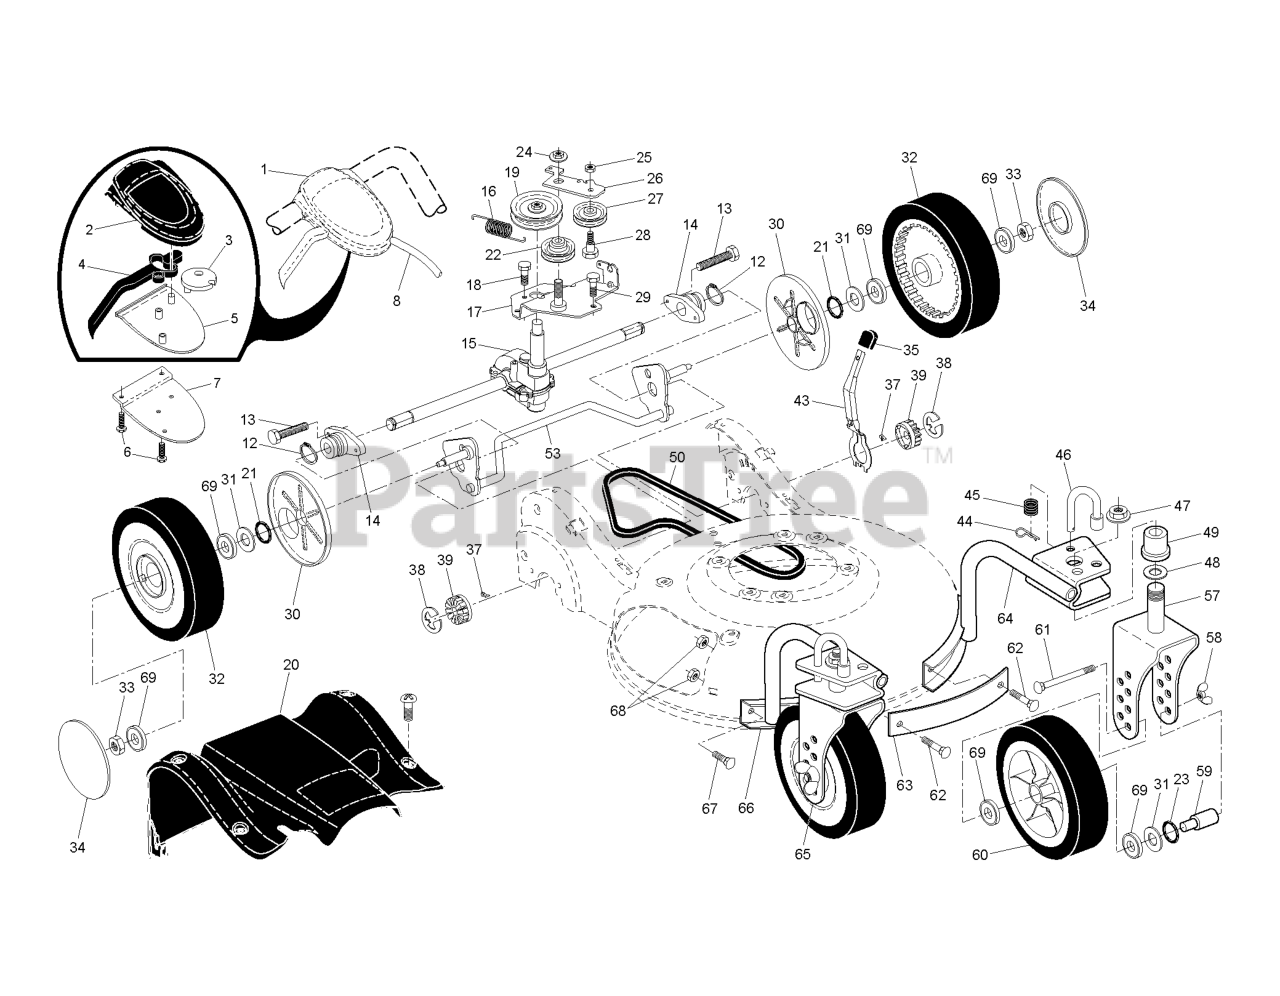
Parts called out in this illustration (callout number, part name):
1	Drive Control Assembly, Complete
2	COVER TOP AUTO WALK CONTROL
3	PULLEY.CAM.DRIVE.CONTROL.HV
4	LEVER.BLACK
5	COVER BOTTOM AUTO WLK CONTROL
6	SCREW, PHILLIPS HEAD 10 X 5/8
7	BRACKET.DRIVE.CONTROL.MOUNT.BL
8	ASM.CABLE.
12	RETAINING RING (2 2)(3 2)
13	HINGE SCREW
14	BEARING / AXLE SUPPORT
15	TRANSMISSION.21.HV.RWGD.AW/EZ
17	BRACKET, GEAR CASE / DRIVE
19	RP PULLEY.DRIVE.EZ
20	COVER.DR.ASM.408006X418.CE
21	O-RING..070X.487.NEOPRENE
22	PULLEY.IDLER.V-BELT
23	O-RING
24	NUT.HEX.FLANGE.3/8-16.LOCKNUT
25	NUT.CENTERLOCK.5/16-
26	ARM.IDLER.BZP
27	IDLER PULLEY
28	SHOULDER BOLT
29	SCREW 14-20 X 5/8
30	DUST COVER, WHEEL
31	WASHER.FLAT.1/2
32	WHEEL.9X2.25.LP.TIGER.BLACK
33	NUT.HEX.FLANGE.3/8-16.LO(3 2)
34	HUBCAP.WHEEL.5.SPOKE.SILVER
35	KNOB.SELECTOR.SPRING.BLACK(3 2
37	PAWL, DRIVE
38	E-RING 7/16 RE
39	PINION.14.TEETH.FGD
43	LEVER, SELECTOR, HEIGHT, REAR
44	SPRING RETAINER
47	NUT.HEX.FLANGE.3/8-16.LOCKNUT
48	WASHER.FLAT.1/2
50	BELT, DRIVE
53	SHAFT.ASM.REAR.TORQUE.HV.BZP
57	BRACKET.WHEEL.ASM.LT.CASTER.OR
58	NUT.WING.5/16-18.YELLOW
60	WHEEL.9X2.25.LP.TIGER.SILVER
61	CARRIAGE BOLT
63	STRAP.FRONT.CASTER.ORANGE
64	SUPPORT.TUBE.ASM.LT
65	BRACKET.WHEEL.ASM.RIGHT.ORANGE
66	SUPPORT.TUBE.ASM.RT
68	NUT
69	BEARING.8".WHEEL
